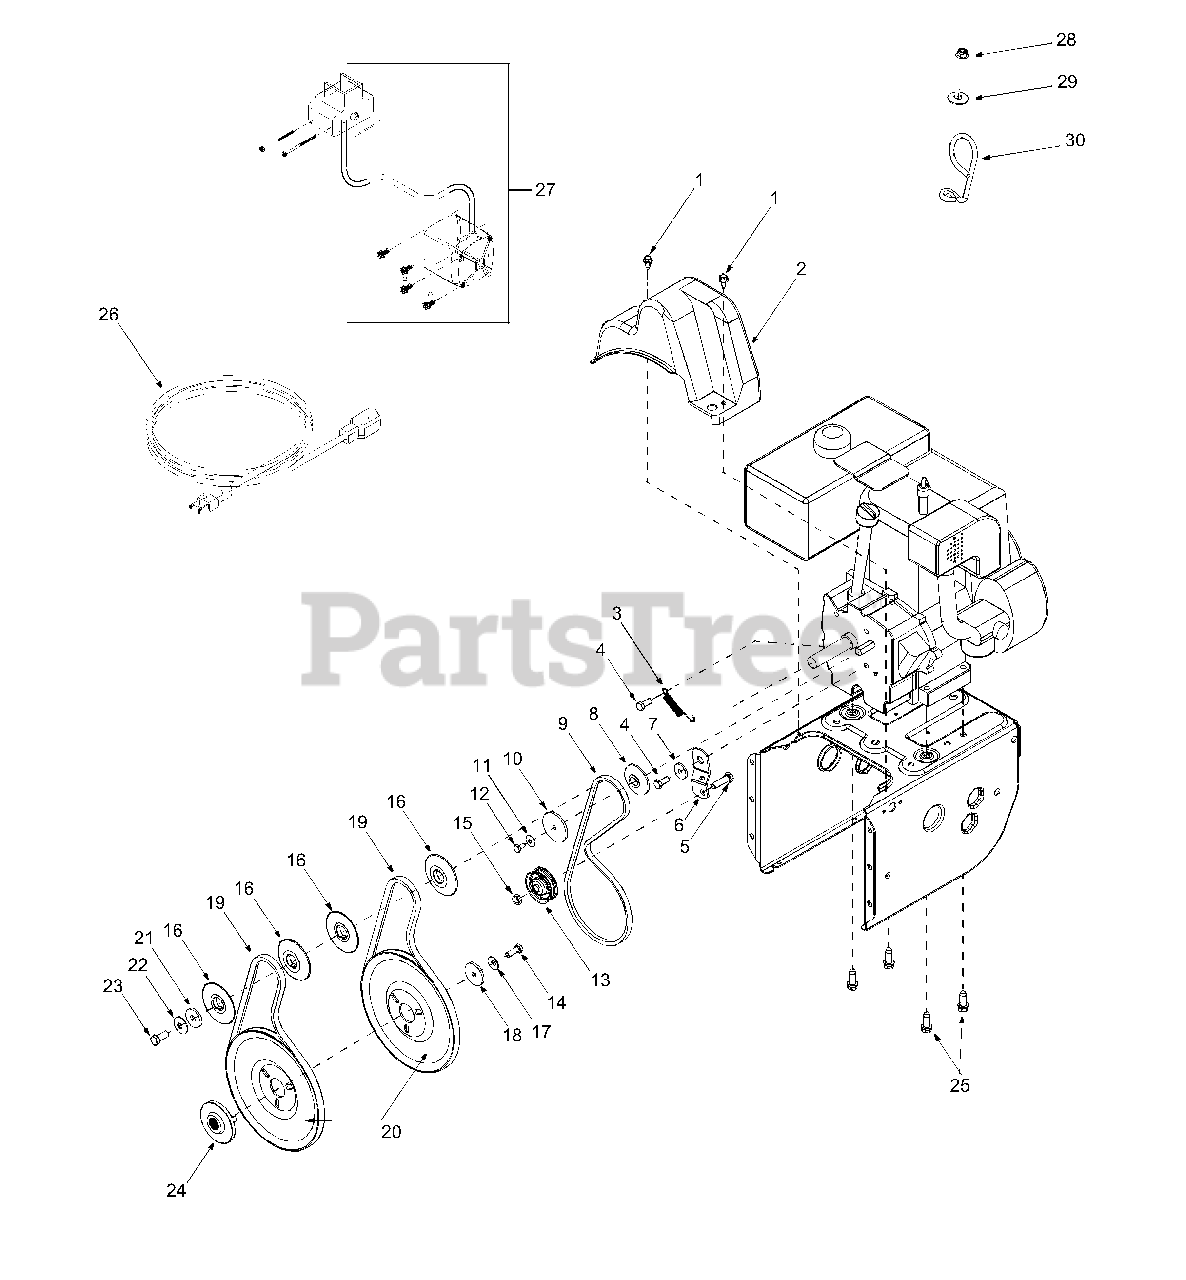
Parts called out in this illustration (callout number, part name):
1	Hex Washer Screw 1/4-20 x .625
3	Extension Spring
4	Hex Screw 5/16-24 x .75
5	Hex Cap Screw 3/8-16 x 1.25
8	Pulley Half
9	V-Belt
12	Hex Cap Screw 1/4-28 x .50
14	Lock Hex Cap Screw 5/16-24
15	Lock Jam Nut 3/8-16
19	Belt
20	Auger Pulley
21	Flat Washer 3/8 x 1.25 OD
23	Hex Cap Screw 3/8-24
24	Adapter Pulley
25	Hex Screw 3/8-16 x 1.0
26	Extension Cord
27	Electric Start Kit
28	Lock Nut, 1/4-20
29	Flat Washer, .28 x .74 x .063
